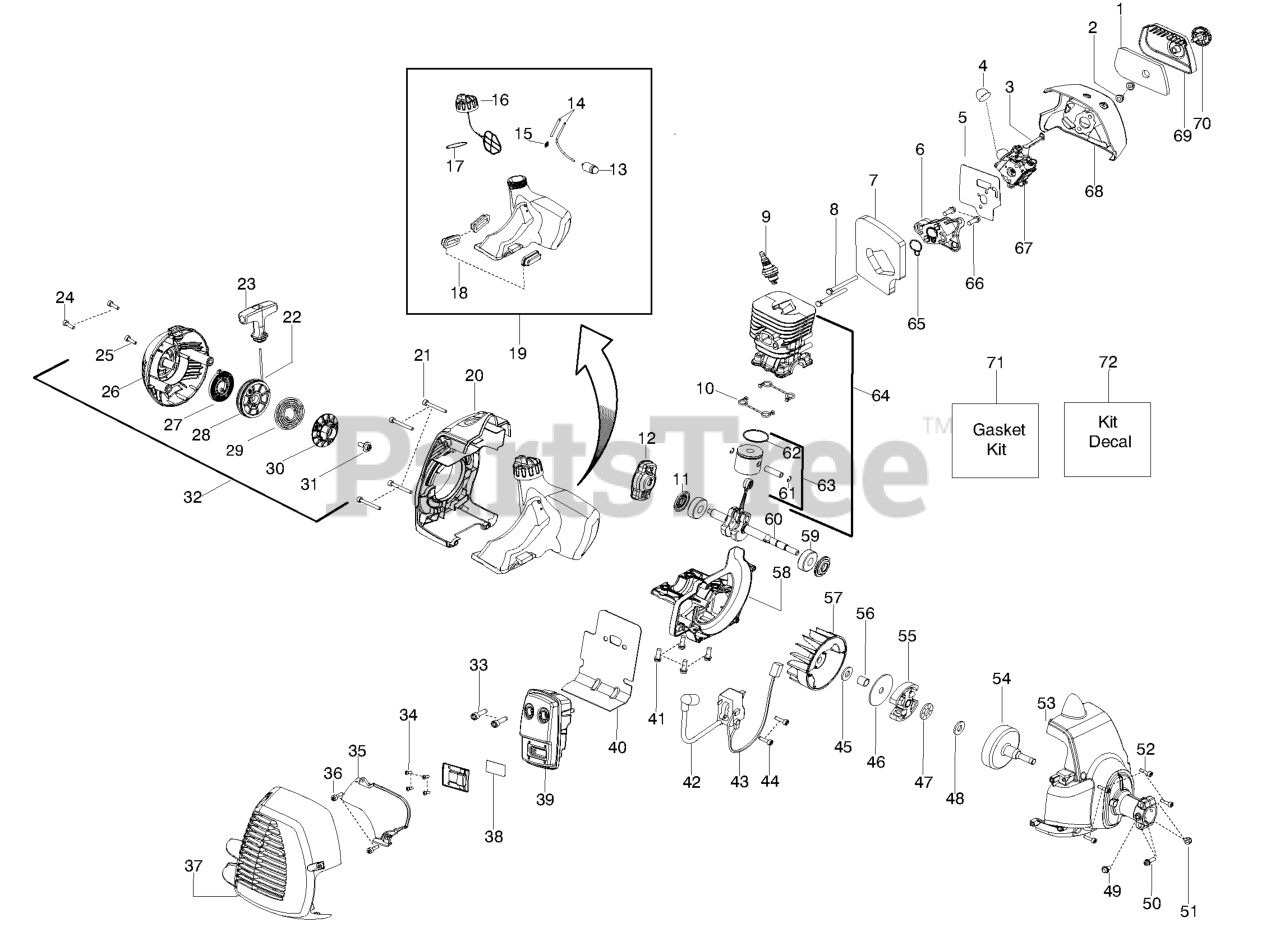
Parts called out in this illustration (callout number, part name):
1	FILTER AIRBOX
3	CHOKE LEVER
4	PURGE BULB ZAMA
5	KIT GASKET CARB 28CC
6	CARB ADAPTOR
7	KIT GASKET 28CC
8	BOLT CARB ADAPTOR
9	Plug-Spark (RCJ-8Y)
10	KIT GASKET 28CC
11	KIT GASKET 28CC
12	STARTER PAWL BRIDGE
13	FUEL PICK-UP ASSY
14	KIT-LINE(FUEL)
15	FUEL LINE FITTING
16	ASSY-CAP W/RETAINER
17	KIT GASKET 28CC
18	ISOLATOR FUEL TANK
19	KIT FUEL TANK HVA
20	KIT STARTER HSG HVA 128
22	KIT ROPE
23	HANDLE - STARTER
24	SCREW M5-0.8X30MM
25	SCREW M4 X 1.75 PT 16MM
26	KIT STARTER HSG HVA 128
27	KIT STARTER SPRING
28	KIT STARTER PULLEY
29	SPRING - DRIVER
30	DRIVER PULLEY
32	ASSY STARTER HSG HVA
33	BOLT MUFFLER
34	SCREW-6-19X5/16PLAST PA
35	SHIELD HEAT
36	SCREW M4 X 1.75 PT 16MM
37	KIT MUFFLER GUARD HVA
38	KIT SPARK ARRESTOR SCREEN
39	KIT MUFFLER LE28
40	KIT GASKET 28CC
41	SCREW-M5-0.8 X 25MM(TAP)
42	IGNITION MODULE MBU-7
43	ASSY MODULE LEAD WIRE
44	SCREW M4 X .70 TT 16MM
45	WASHER CLUTCH
46	WASHER-CLUTCH
47	BEARING THRUST
48	WASHER THRUST
49	Screw
50	Screw
51	LOCKNUT-HEX 10-24
52	SCREW M4 X .70 TT 16MM
53	Assy-Fan Housing
54	ASSY-CLUTCH DRUM
55	ASSEMBLY CLUTCH
56	SPACER FLYWHEEL
58	CRANKCASE CAST LE28
59	BEARING RADIAL BALL (6201)
60	ASSY CRANKSHAFT
61	WRIST PIN RET.
62	RING PISTON
63	KIT - PISTON
64	KIT PISTON CYL
65	KIT GASKET 28CC
66	SCREW-M5-0.8 X 25MM(TAP)
67	KIT CARB
68	RP_AIR BOX
69	COVER-AIR BOX
70	KNOB ASSY AIRBOX COVER
71	KIT GASKET 28CC
